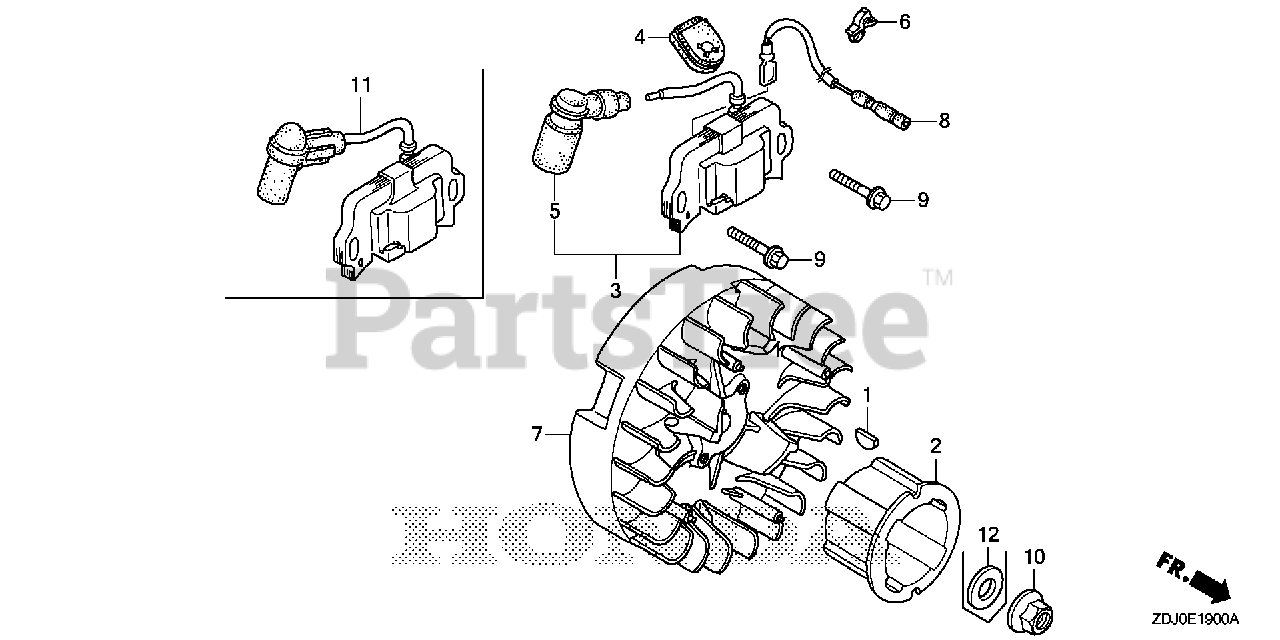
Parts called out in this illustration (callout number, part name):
1	KEY, SPECIAL WOODRUFF (25X18)
2	PULLEY, STARTER
3	COIL ASSY., IGNITION
4	GROMMET, WIRE
5	TERMINAL ASSY., IGNITION
9	BOLT, FLANGE (6X20) (CT200)
10	NUT, SPECIAL (14MM)
